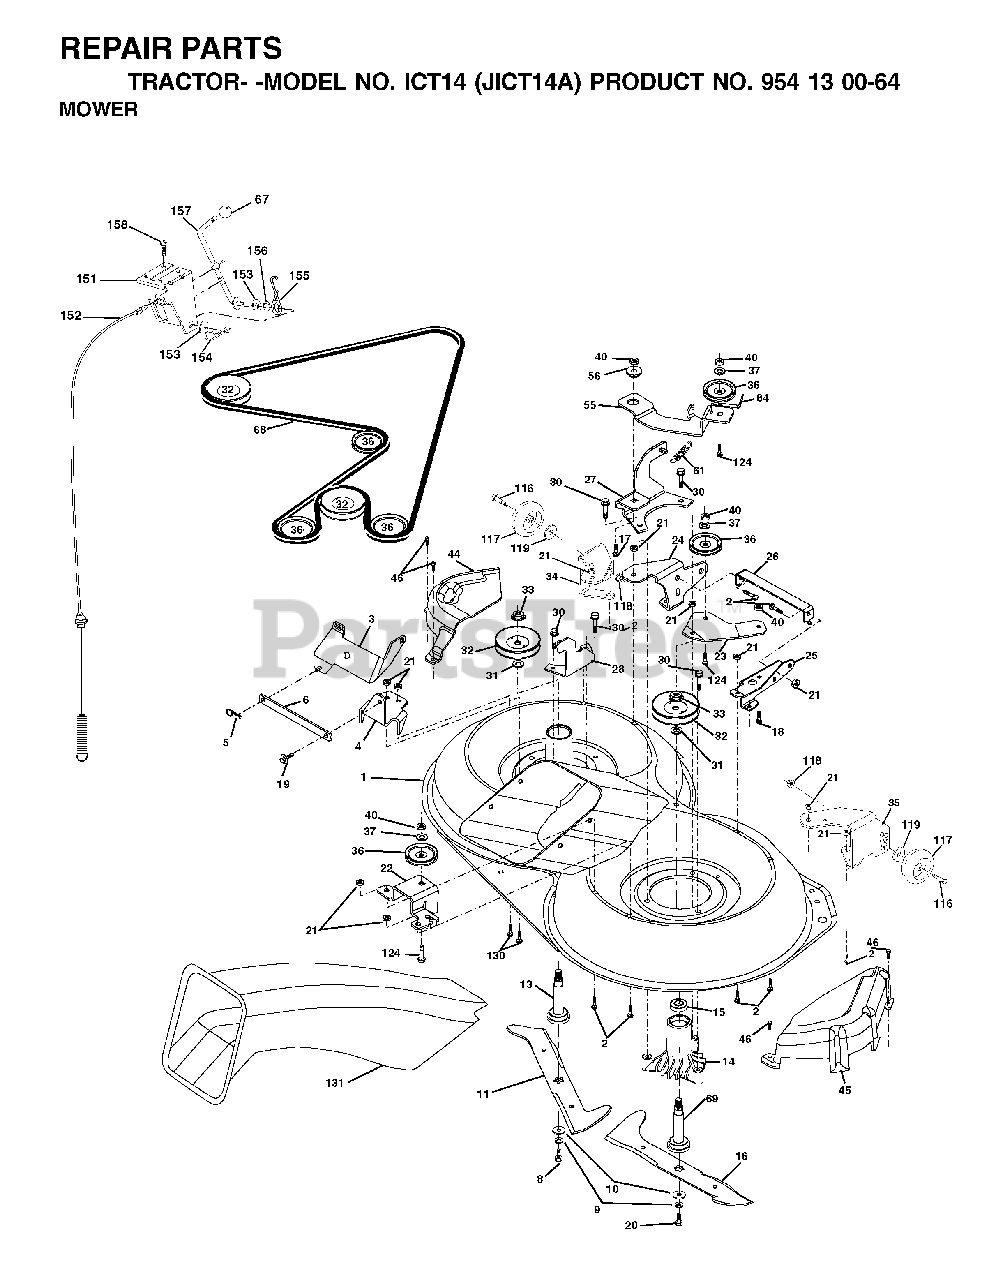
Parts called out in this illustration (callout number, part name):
1	MOWER HOUSING, DECK
2	BOLT
3	BRACKET
5	RETAINER-SPRNG RB
6	BAR SWAY
8	BLADE BOLT
9	LOCKWASHER
10	WASHER.BLADE
11	BLADE-LH 5PT STAR(CTH130)
13	SHAFT ASM VENT
14	HSG MANDREL
16	BLADE RH 6PT STAR(CTH130)
17	BOLT.3/8-14X1.25
19	BOLT SHD 5/16-18
21	LOCKNUT
24	BRACKET
25	BRACKET
26	BRACE
28	BRACKET
30	SCREW, WASHER HEAD
31	WASHER
32	PULLEY, MANDREL
33	NUT, FLG TOPLOCK 9/16"
36	PULLEY.IDLER.4.25
40	LOCKNUT
45	MANDREL COVER
46	SCREW.1/4-20X5/8
55	ARM IDLER
56	SPACER.RETAINER.MOWER
61	SPRING.TENSION.BELT
67	KNOB T (3/8 HOLE)
68	HEX-BELT 92 MOWER 105AA
69	SHAFT.ASM.W/LWR.BRG.RH.THREAD
84	KEEPER, BELT IDLER
116	BOLT, SHOULDER
117	WHEEL GAGE DONUT
118	LOCKNUT
119	WASHER
124	BOLT.3/8-16X1.50
131	CHUTE BAGGER
151	BRACKET, CLUTCH CABLE
153	WASHER FLAT 3/8"
154	SPRING RETAINER
155	SPRING RETENTION LEVER
156	SPACER CLUTCH CABLE
157	ROD CLUTCH CABLE 3/8"
158	SCREW
